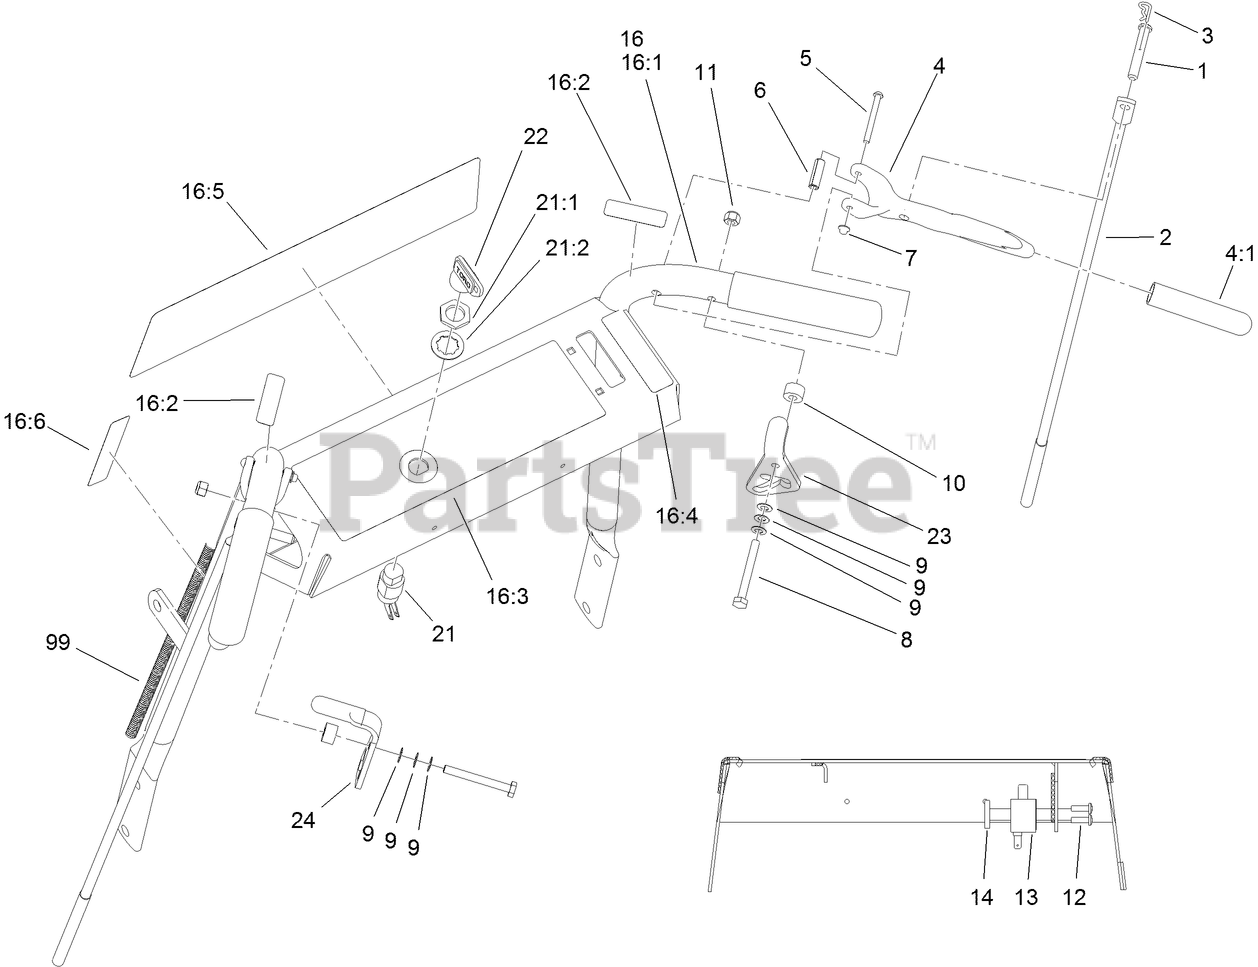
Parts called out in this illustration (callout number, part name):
1	PIN-CLEVIS
2	LINKAGE-WHEEL, DRIVE
3	PIN-COTTER
4	DRIVE LEVER ASM
4:1	GRIP-LEVER, DRIVE
5	PIN-LEVER, DRIVE
6	PIN-ROLL
7	NUT-PUSH
8	SCREW-HH
9	WASHER-SPRING
10	SPACER
11	NUT-LOCK, NI
12	SCREW-PPH
13	SWITCH-OPEN, NORMALLY
14	PLATE-TAPPED
16	HANDLE ASM
16:1	PISTOL GRIP HANDLE ASM
16:2	DECAL-LOCK, NEUTRAL
16:3	DECAL-WARNING
16:4	DECAL-THROTTLE
16:6	DECAL-ENGAGE, DECK
21	SWITCH-ON / OFF
21:1	NUT-HH
21:2	WASHER-LOCK
22	KEY-IGNITION
23	LATCH-RH THUMB,W/GRIP
24	LATCH-LH THUMB,W/GRIP
99	HARNESS-WIRE
